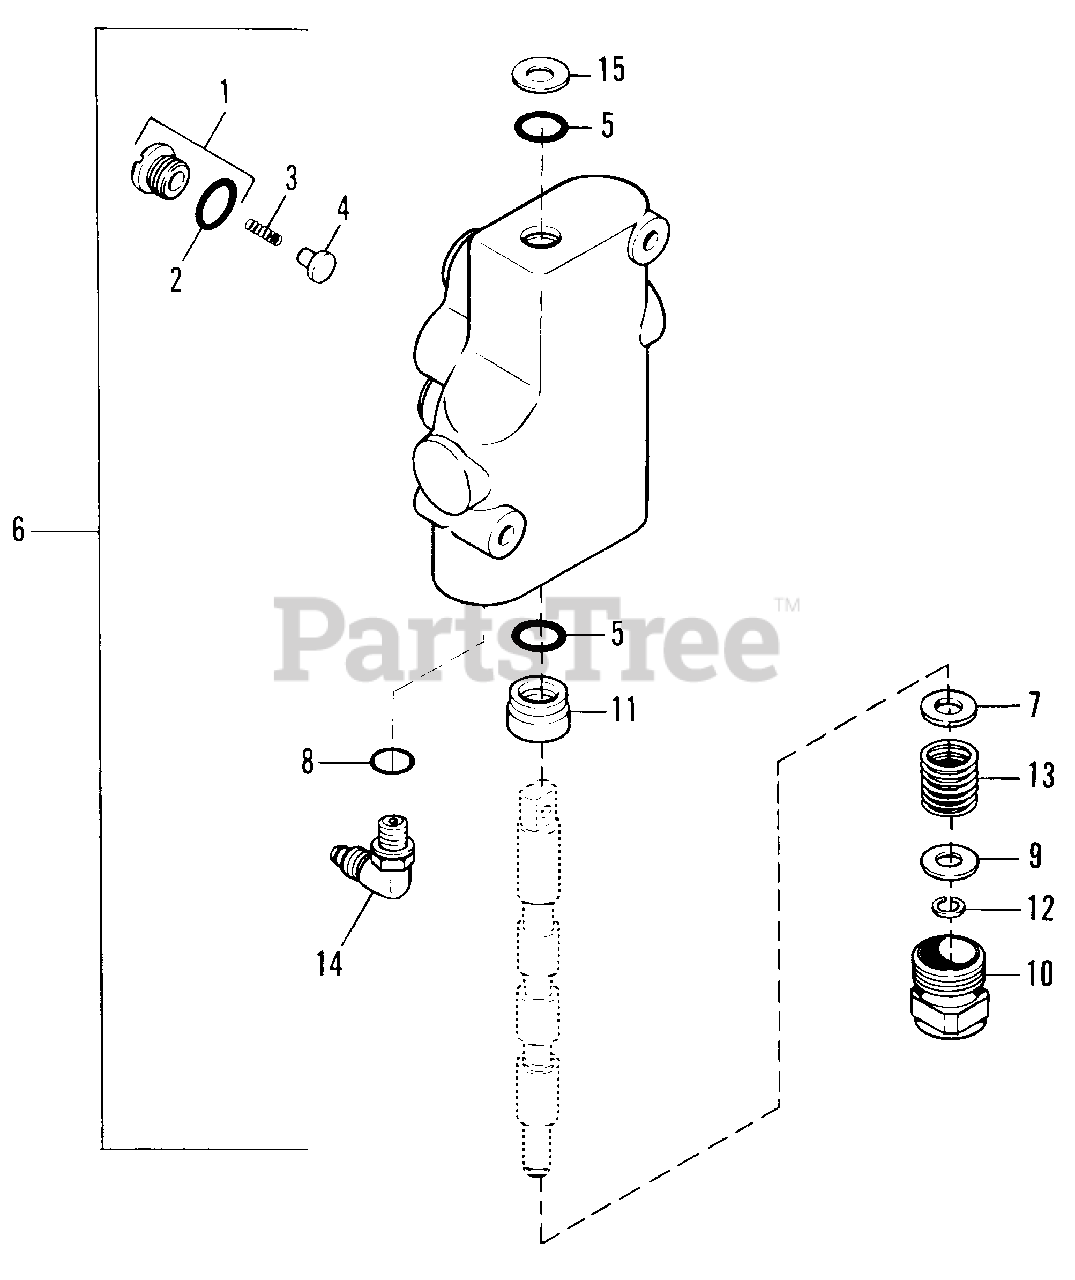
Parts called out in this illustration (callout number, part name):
1	PLUG ASSEMBLY
4	PLUNGER, Lift Check
6	VALVE ASSEMBLY
12	RING, Retaining
15	WIPER SEAL
15	SEAL KIT (Includes Ref. No. 2, 5, 8, 15)
